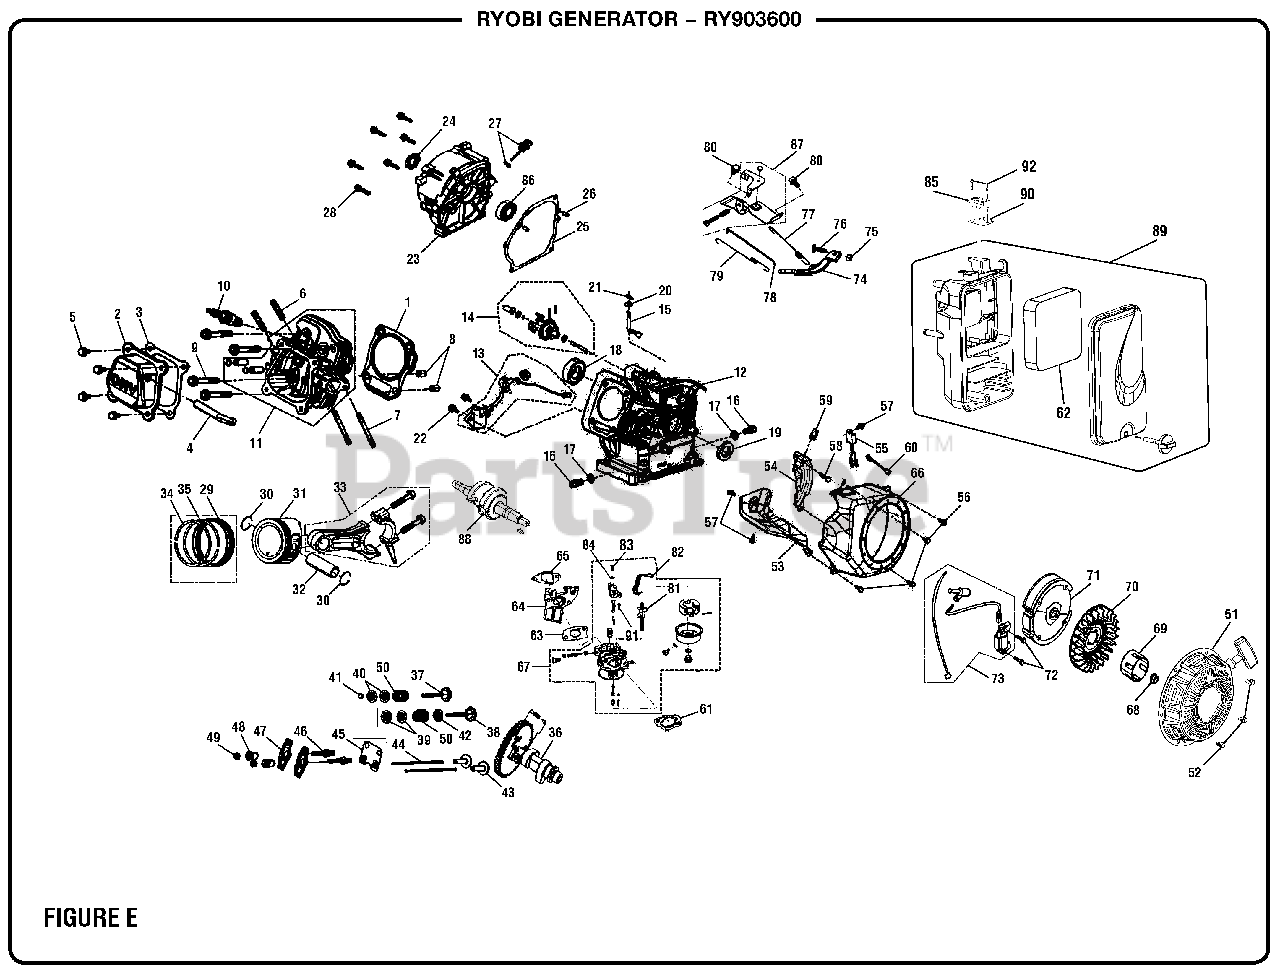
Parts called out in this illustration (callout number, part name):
1	Cylinder Head Gasket
2	Cylinder Head Cover Assembly
3	Cylinder Head Cover Gasket
9	Cylinder Head Bolt
11	Cylinder Head Assembly
12	Crankcase Assembly
13	Engine Oil Sensor
14	Governor Gear Assembly
16	Drain Plug Bolt
18	Ball Bearing
23	Crankcase Cover
24	Screw (M6 x 10 mm, Pan Hd.)
25	Crankcase Gasket
27	Oil Dipstick Assembly
30	Piston Pin Clip
35	The Second Ring
36	Camshaft Assembly
39	Valve Spring Seat
40	Valve Lock Clip
45	Lifter Stop Plate Assembly
46	Valve Adjusting Bolt
48	Valve Adjusting Nut
51	Recoil Starter Assembly
53	Cylinder Body Shroud
60	Stop Engine Wire
61	Air Cleaner Gasket
63	Carburetor Gasket
64	Carburetor Insulator Plate
65	Carburetor Insulator Gasket
67	Carburetor Assembly
71	Flywheel Assembly
74	Governor Support Assembly
76	Governor Support Bolt
77	Governor Spring
79	Throttle Valve Return Spring
81	Choke Lever
82	Control Lever
83	Bolt (M4 x 10 mm, Pan Hd.)
84	Washer (ID4.3 x OD10 x 0.9t)
85	Engine Stop Switch
86	Screw (M2.9 x 16 mm, Pan Hd.)
87	Throttle Arm Assembly
88	Crankshaft Assembly
89	Engine Air Box Assembly
